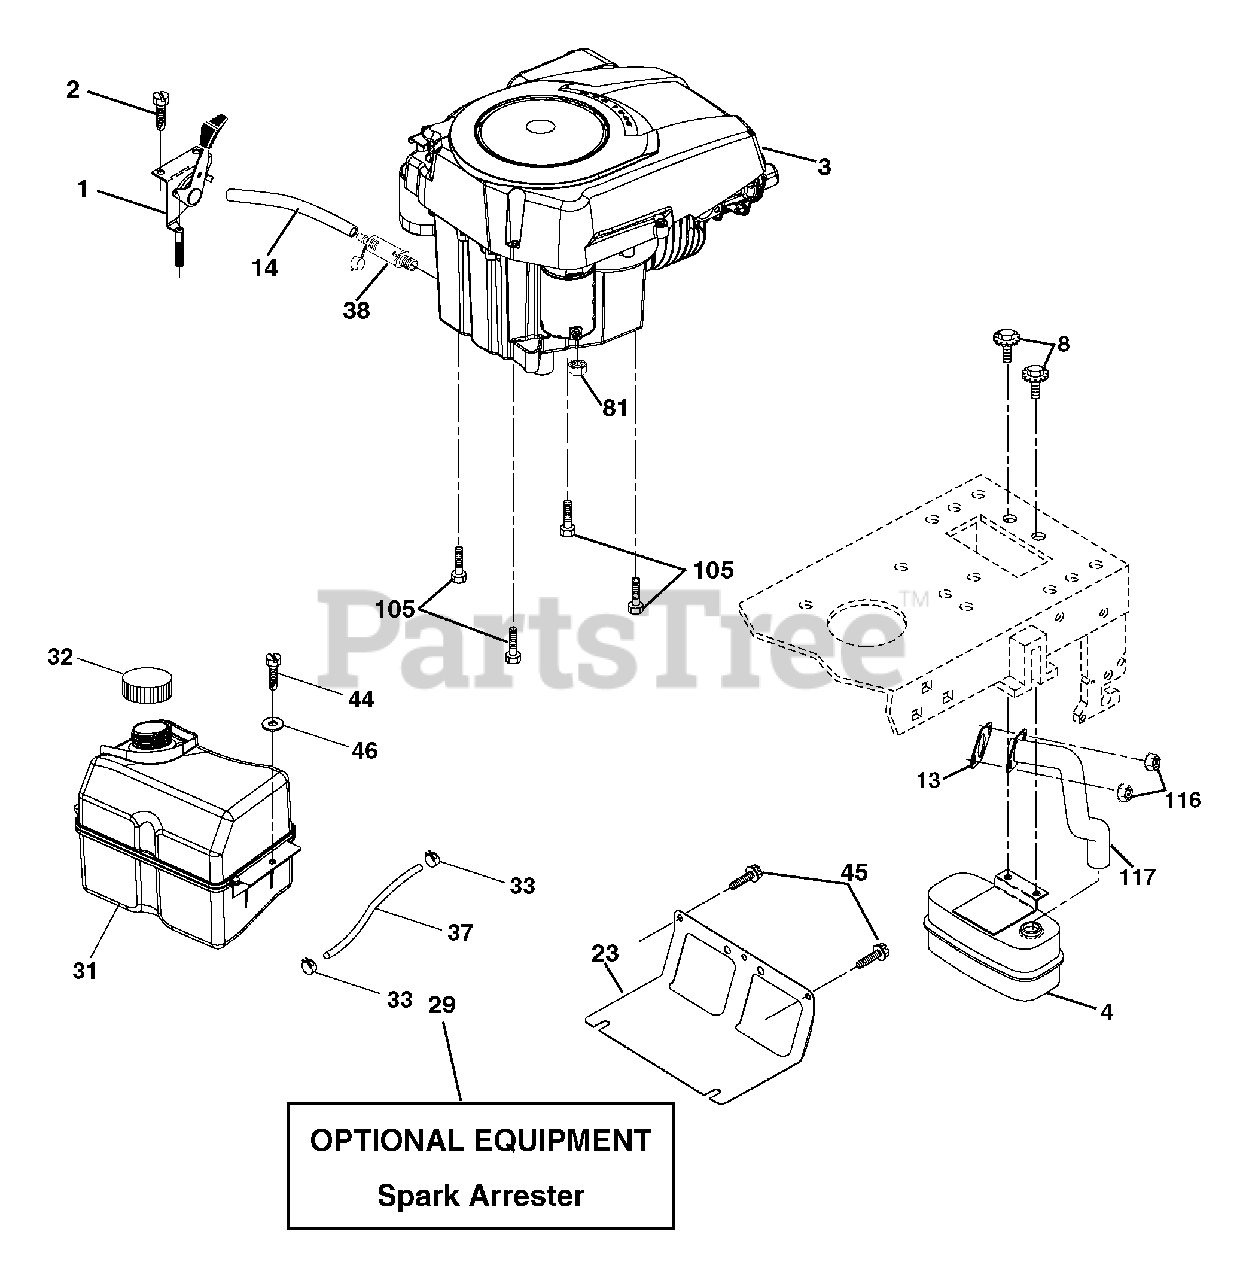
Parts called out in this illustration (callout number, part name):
1	Control, Throttle
2	Screw Hex Thd Cut 1/4-20 x 1/2
4	Muffler
8	Bolt 5/16-18 unc x 3/4 w/Sems
13	Muffler Gasket
14	Tube Oil Drain
23	Shield, Browning/Debris Guard
29	Arrester, Spark
31	Tank, Fuel
32	Cap, Fuel
33	Clamp, Hose Blk
37	Line, Fuel
38	Plug Drain Oil Easy
44	Screw Hex Wsh Thdrol 1/4-20 x 3/4
45	Screw Hex Wsh Thdrol 3/8-16 x 3/4
46	Washer 9/32 x 7/8 x 16 Ga.
81	Nut Keps Hex 1/4-20 unc
105	Screw 3/8-16 x 1 Smgml Tap/R
116	Nut Hex Flange Toplock M8-1.25
117	Tube Exhaust
